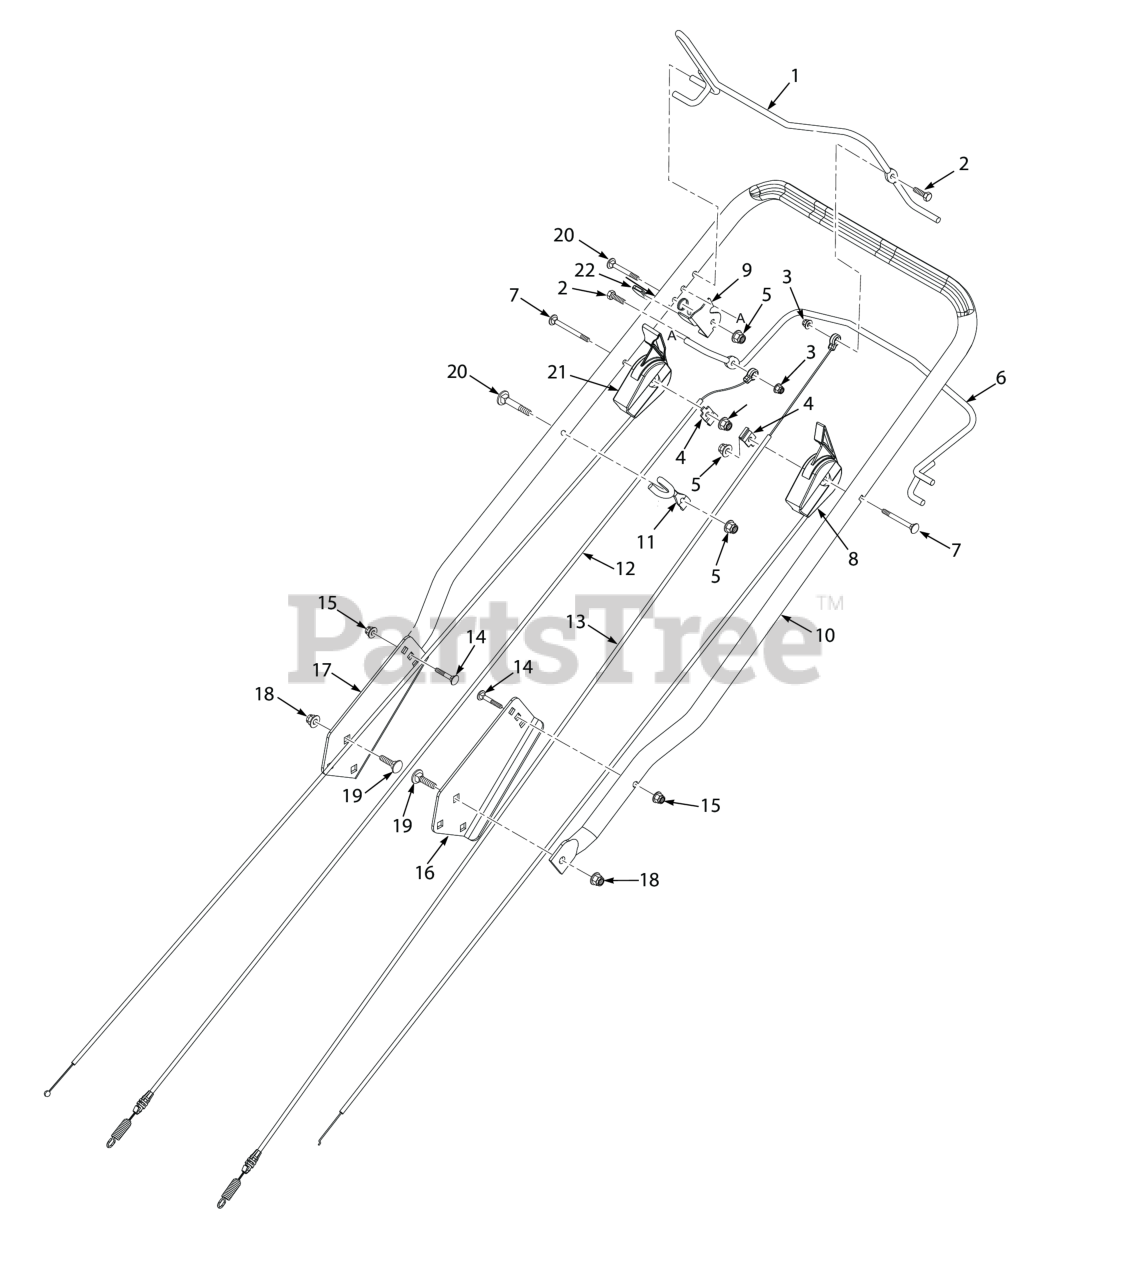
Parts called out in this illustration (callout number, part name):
1	Top Bail Weldment
2	Bolt, Shoulder 5/16 x 3/8"
3	Bolt, Hex Hd. 1/2-13 x 9-1/2"
4	Clamp, Cable
5	Nut, Flanged Elastic Stop 1/4-20
6	Bottom Bail Weldment
7	Bolt, Carriage 1/4-20 x 2"
8	Cable, Throttle
9	Latch, PTO
10	Handle
11	Guide, Pull Rope
12	Cable, Clutch
13	Cable, Drive
14	CARR BOLT, 5/16-18 X 1.75
15	Nut, Flange Head Elastic Stop 5/16-18
16	Handle Support Bracket, LH
17	Handle Support Bracket, RH
18	Nut, Flange Elastic Stop Nut, 3/8-16
19	Carriage Bolt, 3/8-16 x 1.0"
20	Bolt, Carriage 1/4-20 x 1-3/4"
21	Cable, Speed Select
22	Grip, PTO Latch
